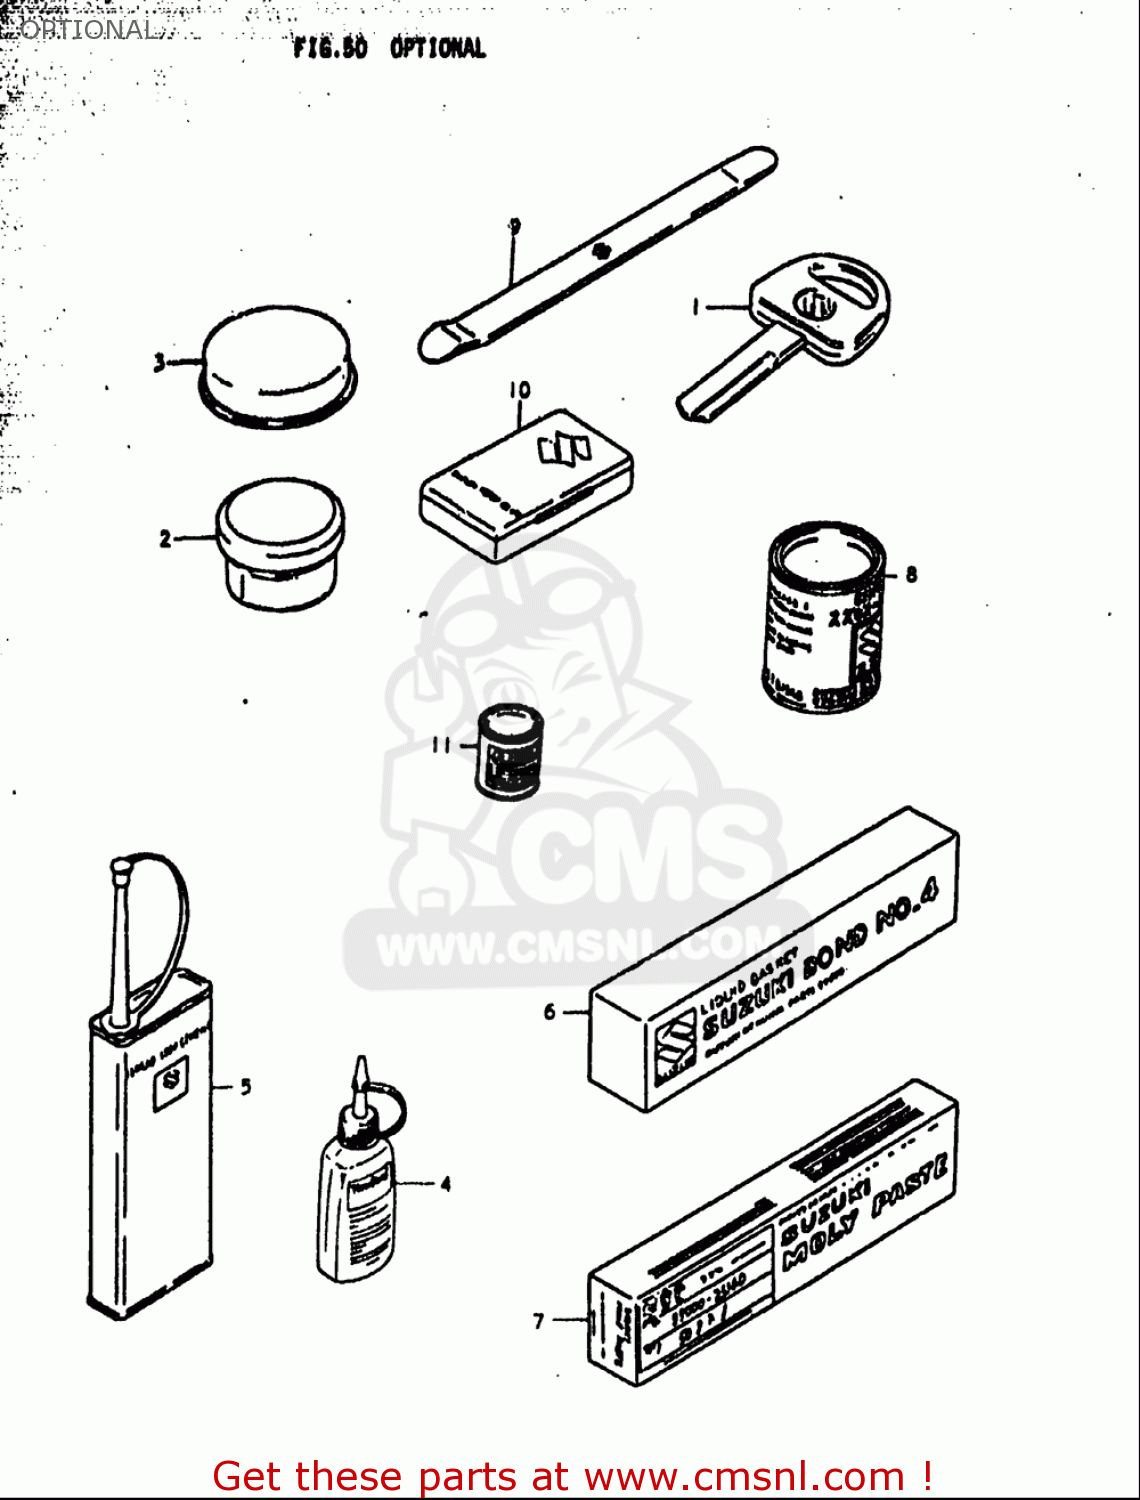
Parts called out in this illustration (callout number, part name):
1	KEY,BLANK
2	GREASE,PBC FOR BRK PAD 20G
3	GREASE,SILICON 20G
4	THREAD LOCK NO.1303B PURPL 50G
5	THREAD LOCK NO.1401 CLEAR 200G
6	BOND 1104
7	SUZUKI MOLY PASTE
8	GREASE(C)EP2 LITHIUM 150G
9	LEVER,TIRE
12	GASKET SET
